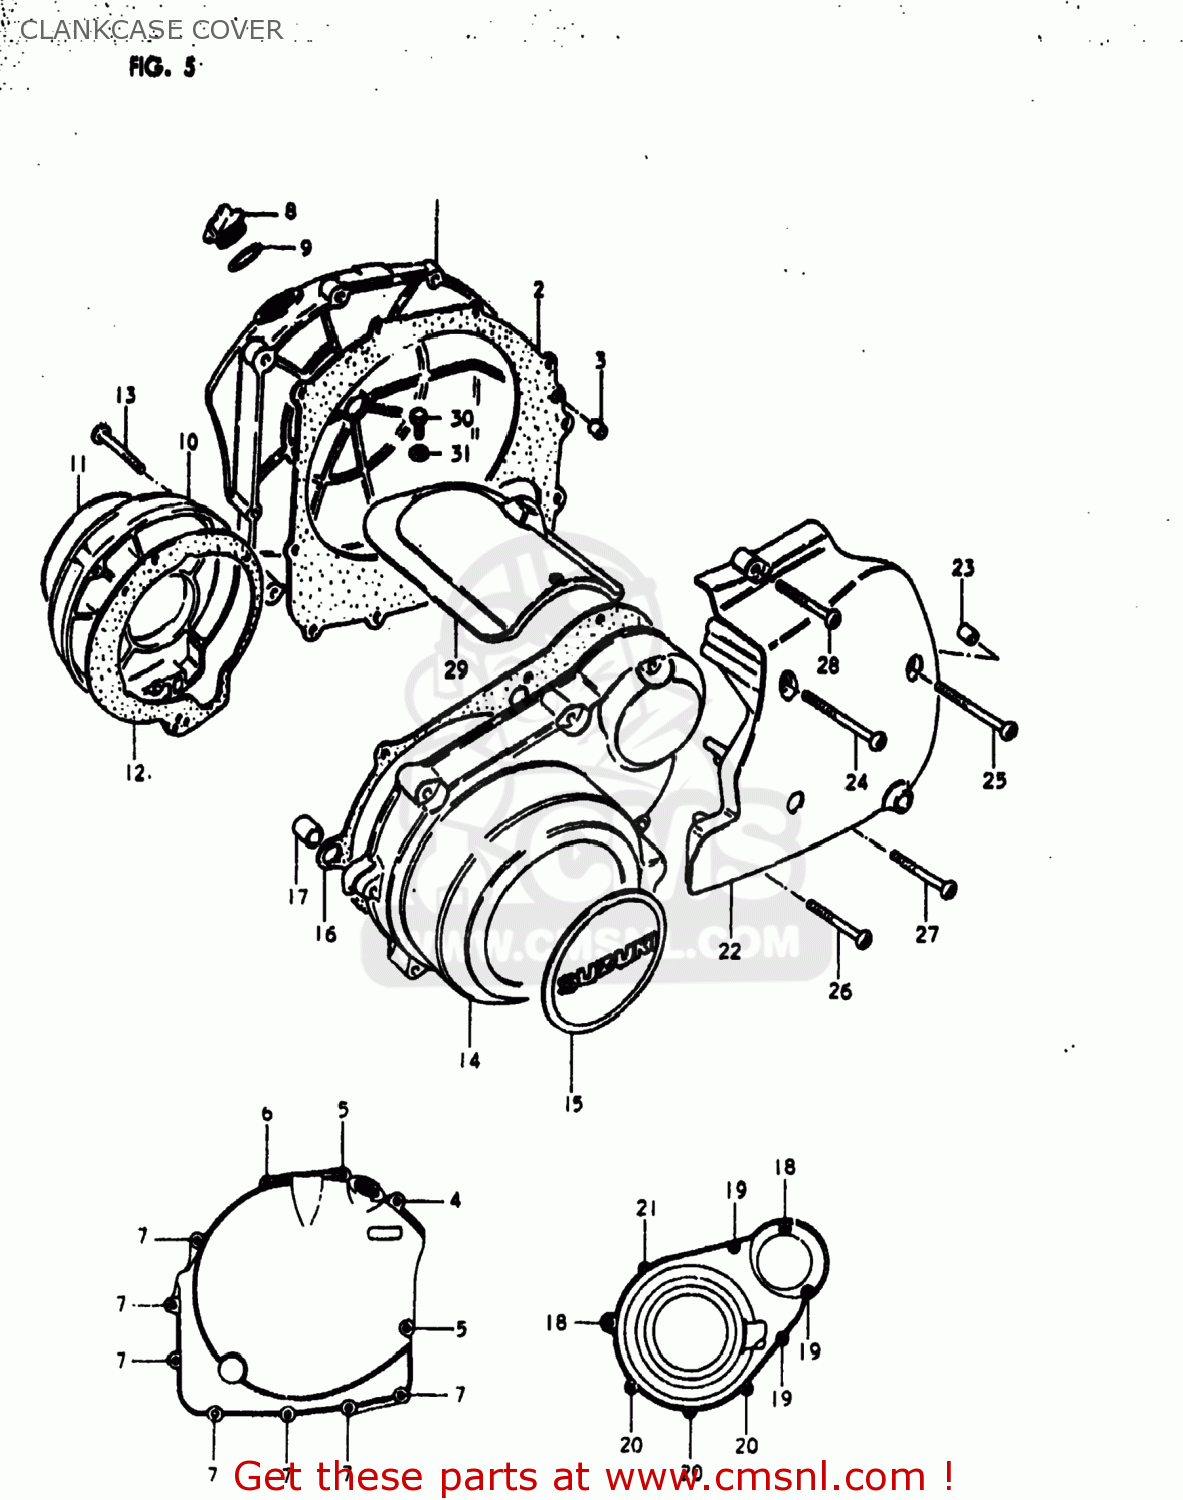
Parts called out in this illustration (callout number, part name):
1	COVER,CLUTCH
2	GASKET,CLUTCH COVER (MCA)
3	PIN
4	SCREW (6X35)
5	SCREW 6X30
6	SCREW
7	SCREW
8	CAP
9	O RING(D:2.2,ID:32)
10	COVER,CONTACT BREAKER
11	EMBLEM
12	GASKET,CONTACT BREAKER COVER (NAS)
13	SCREW
14	COVER
15	EMBLEM
16	GASKET,MAGNETO COVER (MCA)
17	PIN
18	SCREW (6X45)
19	SCREW
20	SCREW (6X35)
21	SCREW 6X30
22	COVER,ENGINE SPROCKET
23	PIN
24	SCREW(6X100)
25	SCREW 6X85
26	SCREW 6X70
27	SCREW
28	SCREW 6X30
29	COVER,STARTER MOTOR
30	BOLT
31	WASHER
